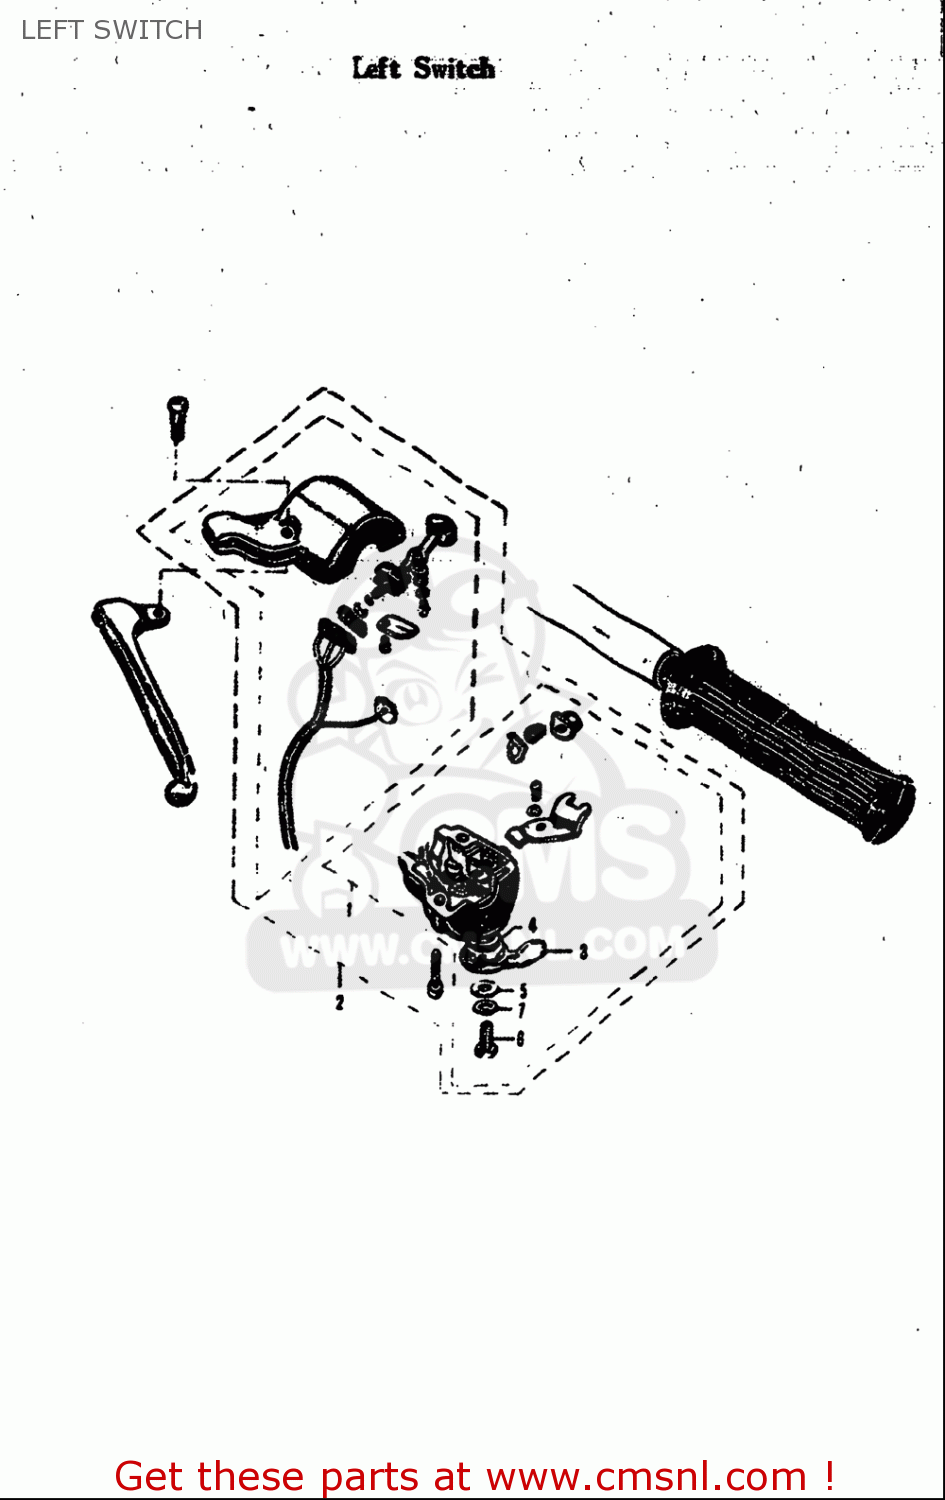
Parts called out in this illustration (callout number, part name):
3	LEVER,STARTER
4	WASHER,ADJUSTER
5	WASHER(6.5X16X1)
